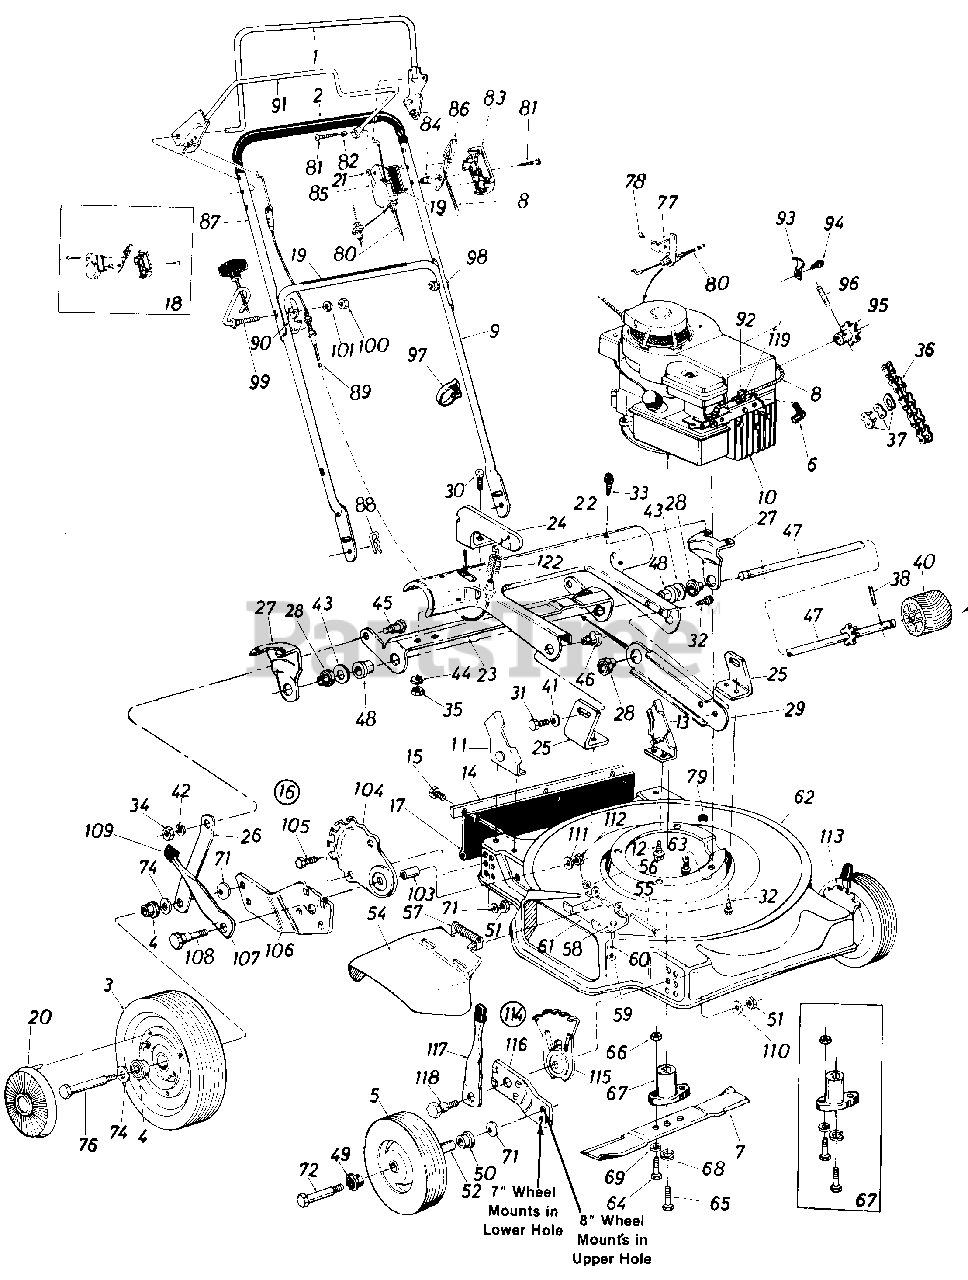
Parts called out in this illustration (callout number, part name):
1	Control Handle Ass'y.-L.H.
2	Grip
3	Rear Wheel Ass'y. Comp.- 9 x 1.75
4	Flange Brg.-1/2" I.D.
5	Front Wheel Ass'y. Comp.
6	Spark Plug Boot
7	Blade 22"
8	Throttle Wire-53.0"
9	Lower Handle (Chrome)
10	Engine
11	Handle Brkt. Ass'y.-R.H.
12	Hex Wash. Hd. B"-Tap Scr. 5/16-18 x .50" Lg.
13	Handle Brkt. Ass'y.-L.H.
14	Retainer Strip
15	Hex AB-Tap Scr. 1/4 x .62"
16	R.H. Height Adj. Comp.
17	Rear Flap Ass'y.
18	Kit-Control Housing Comp.
19	Control Labels
20	Hub Cap
21	Flat Wash. .203" I.D. x .406" O.D.
22	Pinion Pivot Cover 22"
23	Cam
24	Engagement Arm
25	Pivot Brkt.
26	Link
27	Axle Brkt.
28	Flanged Ball Brg..500" I.D.
29	Brg. Support
30	Carriage Bolt 1/4-20 x .50" Lg .
31	Hex Bolt 3/8-16 x .50" Lg.
32	Hex "B"-Tap Scr. 1/4" x .38" Lg.
33	Hex Wash. Hd. "AB"-Tap Scr. 1/4" x .62" Lg.
34	Hex Nut 5/16-18 Thd.
35	Hex Nut 1/4-20 Thd.
36	#48 Chain 1/2" Pitch 49 Links
37	#48 Master Link
38	Spring Pin Spir. 3/16" Dia. x 1.25" Lg.
40	Drive Pinion
41	Bell-Wash. .400" I.D. x .88" O.D. x .060
42	L-Wash. 5/16" I.D.
43	Fl-Wash. .531" I.D. x .930" O.D. x .050
44	L-Wash. 1/4" I.D.
45	Shld. Bolt .437" Dia. x .162
46	Shld. Nut .625" Dia. x .162
47	Pinion Shaft w/7 Tooth Sprocket
48	Flange Brg. .506" I.D.
49	Bearing
50	Bearing
51	Hex Nut 3/8-16 Thd.
52	Spacer (Used w/Ball Brgs. Only)
54	Chute Deflector Ass'y.-Comp.
55	Pivot Pin
56	Cap Speed Nut 1/4" Rod
57	Torsion Spring
58	Hex Bolt 1/4-20 x .50" Lg.
59	Hex Nut 1/4-20 Thd.
60	L-Wash. 1/4" I.D.
61	Hinge Plate
62	22" Deck Ass'y.
63	Hex Wash. Hd. TT-Tap Scr. 3/8-16 x 1.0" Lg.
64	Hex Bolt 5/16-24 x 1.00" Lg. (Grade 5)
65	Hex Bolt 3/8-24 x 2.25" Lg. (Grade 5)
66	Hex Nut 5/16-24 Thd.
67	Blade Adapter Kit
68	L-Wash. 3/8" I.D.-H.D.
69	L-Wash. 5/16" I.D.
71	Bell-Wash. .400" I.D. x .88" O.D.
72	Front Axle Bolt
74	Fl-Wash. .531" I.D. x .93"O.D.
76	Rear Axle Bolt
77	Cable Bracket
78	Pop Rivet .156" Dia. x .379
80	Control Cable-39.0"
81	Truss Mach. Self-Tap Scr. #12 x 1.50" Lg.
82	Spacer.23" I.D.
83	Control Panel Half
84	Control Disc Pin
85	Clutch Panel Half
86	Throttle Control Lever
87	Upper Handle (Chrome)
88	Hairpin Cotter
89	Clutch Cable w/Spring
90	Cable Mtg. Brkt.
91	Drive Control Handle
92	Casing Clamp
93	Casing Clamp
94	Hex "B"-Tap Scr. #10 x .38"
95	10 Tooth Sprocket Ass'y.
96	Spiral Pin 3/16" Dia. x 1.00"
97	Cable Tie
98	Curved Hd. Carriage Bolt 5/16-18 x 1.38" Lg.
99	Rope Guide Bolt
100	Hex Nut 5/16-18 Thd.
101	L-Wash. 5/16" I.D.
103	Spacer.395" I.D. x .503" O.D. x .562" Lg.
104	Index Plate
105	Hex Bolt 3/8-16 x .75" Lg.
106	Pivot Bar R.H.
107	Spring Lever
108	Shoulder Bolt .500" Dia. x 3.75" Lg.
109	Spring Lever Knob
110	Bell-Wash. .39 I.D. x 1.4 O.D.
111	Bell-Wash. .336" I.D. x .860 O.D.
112	Hex L-Nut 5/16-18 Thd.
113	Height Adj. Ass'y.-Comp. -L.H.
114	Height Adj. Ass'y.-Comp. -R.H.
115	Height Adj. Plate
116	Pivot Bar
117	Spring Lever Ass'y. w/Knob
118	Shoulder Bolt .500" Dia. x .375" Lg.
119	Hex Wash. Hd. AB-Tap Scr. #8 x .38" Lg.
122	Compression Spring .47" O.D. x 1.93" Lg.
